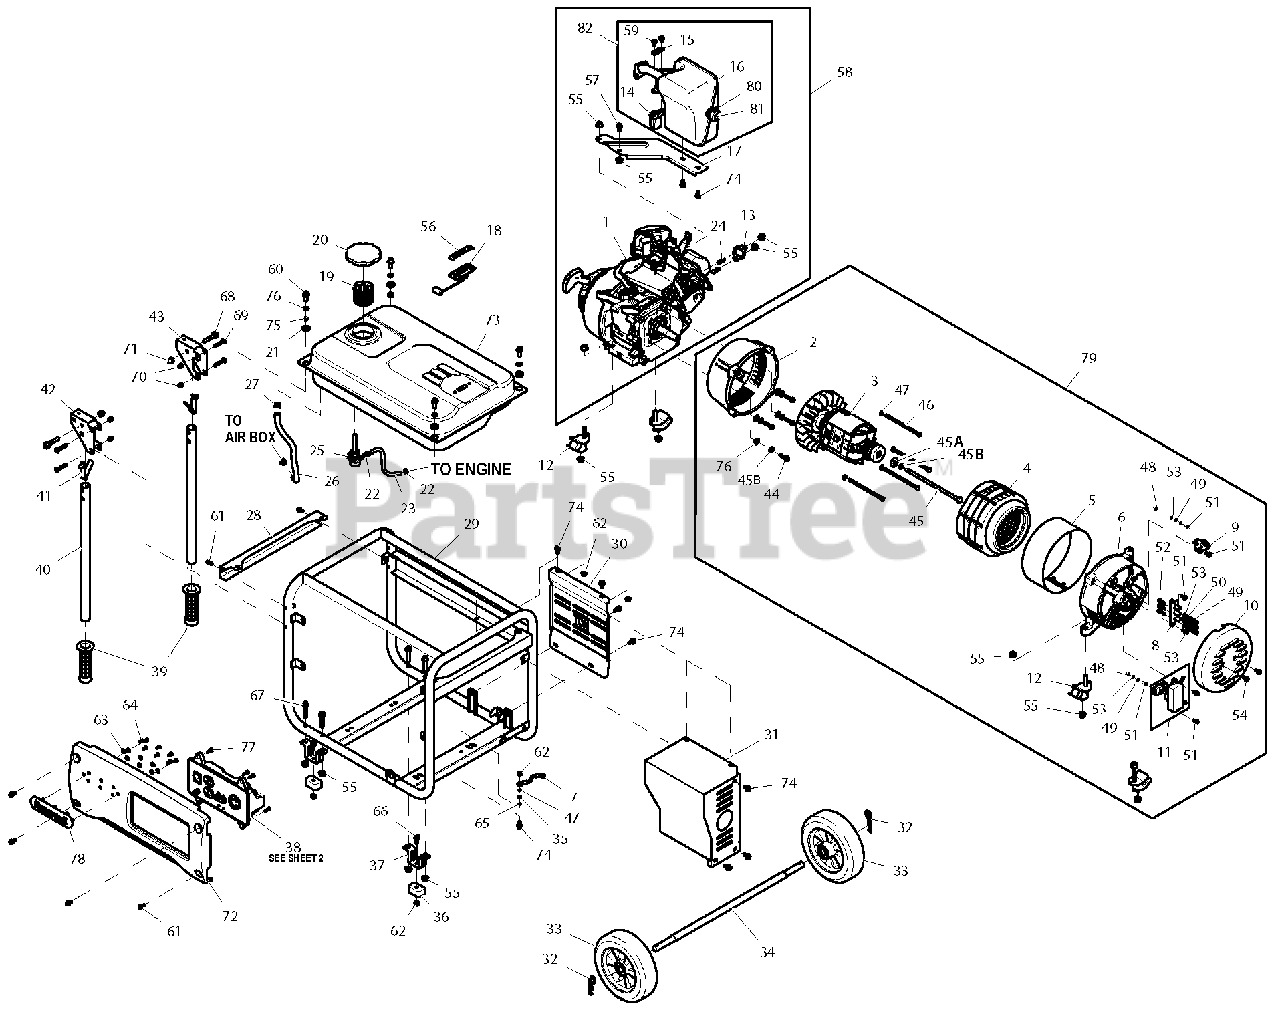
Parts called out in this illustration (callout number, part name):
1	ENGINE 208 PS UP
2	ADAPTOR CASTING,ENG/ALT 3250W
3	ROTOR ASSY
4	STATOR ASSY
5	WRAPPER 620X70
6	REAR BEARING CARRIER 190
7	WIRE ASSY GND ALT TO BASE
8	REAR WIRING FRAME ORANGE
9	ASSEMBLY BRUSH 3.25KW PORTABLE
10	COVER,ALTERNATOR 3.25KW
11	AVR 3.25 KW
12	VIB MOUNT 35 X 15 X M8-1.25
13	GASKET MUFFLER 163/208CC
14	AIR VALVE 2010
15	GASKET AIR VALVE 2010 CARB
16	WELDMENT MUFFLER CAT H3250
17	BRACKET,MUFFLER MNT 163/208CC
18	FUEL GAGE, 90MM LONG ARM
19	FILTER, FUEL
20	FUEL CAP,NOT VENTED, BLACK CAP
21	RUBBER MOUNT 8 ID X 5 HGT
22	CLAMP HOSE BAND SPRING .38
23	FUEL HOSE,4.5 ID,8.5 OD,160 LG
24	STUD M8-1.25/10MM X 30 G5 ZINC
25	FUEL VALVE SWIVEL NUT M16
26	HOSE, 7.5 ID, 13.5 OD, 300 LG
27	CLAMP HOSE BAND .53
28	WLDMNT CRADLE END PANEL H3250
29	CRADLE WELDMENT H3250
30	SIDE MUFFLER SHIELD H3250
31	INSIDE MUFFLER SHIELD H3250
32	COTTER HAIRPIN 2.56 X .80
33	WHEEL, 8" NEVER-FLAT 3.25KW UP
34	AXLE, SOLID 3.25KW PORTABLE
35	WASHER FLAT M6
36	RUBBER FOOT RECTANGLE
37	BENT FOOT 3250W HONEYWELL
38	ASSY CONTROL PANEL
39	GRIP HANDLE 3250W HONEYWELL
40	HANDLE H3250 PORTABLE
41	SNAP BUTTON - .437" DIA. HEAD
42	BRACKET HANDLE H3250 RH
43	BRACKET HANDLE H3250 LH
44	SCREW HHFC M8-1.25 X 25 W/M10
45	SCREW HHFC 5/16-24 X 8.27
45A	WASHER FLAT .344ID X 1.0OD
45B	WASHER LOCK M8 SS
46	SCREW HHC M6-1.0 X 130
47	WASHER LOCK M6-1/4
48	WASHER LOCK INT M5 SS
49	WASHER LOCK M5 SS
50	NUT HEX M5-0.8 G8 CLEAR ZINC
51	SCREW HHFC M5-0.8 X 16
52	SCREW HHC M5-0.8 X 20 G8.8
53	WASHER FLAT M5 SS
54	SCREW HHFC M5-0.8 X 12
55	NUT HEX FL WHIZ M8-1.25
56	PLATE, FUEL GAGE
57	SCREW HHFC M8-1.25 X 35 G8.8
58	ENGINE 208 PS W/MLFR HNYWL
59	SCREW PPHM M6-1.0 X 12 SEMS
60	SCREW HHFC M8-1.25 X 20 W/M10
61	SCREW HHFC M6-1.0 X 12 W/M5
62	NUT HEX FL WHIZ M6-1.0
63	WASHER FLAT #8 ZINC
64	SCREW PPPH #8-16 X 0.40" BZC
65	WASHER LOCK EXT M6 CLEAR ZINC
66	SCREW HHFC M6-1.0 X 20 G8.8
67	SCREW HHFC M8-1.25 X 40 W/M10
68	SCREW HHFC M8-1.25 X 43
69	CHB M6-1.00 X 37 MM LONG
70	CAP NUT M6-1.00 BLACK ZINC
71	CAP NUT M8-1.25 BLACK ZINC
72	PNL PLASTIC SIDE C-PNL HW3250
73	WELDMENT FUEL TANK H3250
74	SCREW HHFC M6-1.0 X 14 G8.8
75	ANTI-CRUSH 8OD 6.2ID 5LG
76	WASHER FLAT M8 SS
77	SCREW PPPH #8-16 X .66" BZC
78	BADGE SIDE PANEL H3250
79	ASSY ALTERNATOR 3250W PORTABLE
80	CLAMP HOSE #16 .87-1.50
81	SPARK ARRESTOR, 163/208CC
82	ASSY MUFFLER H3250
